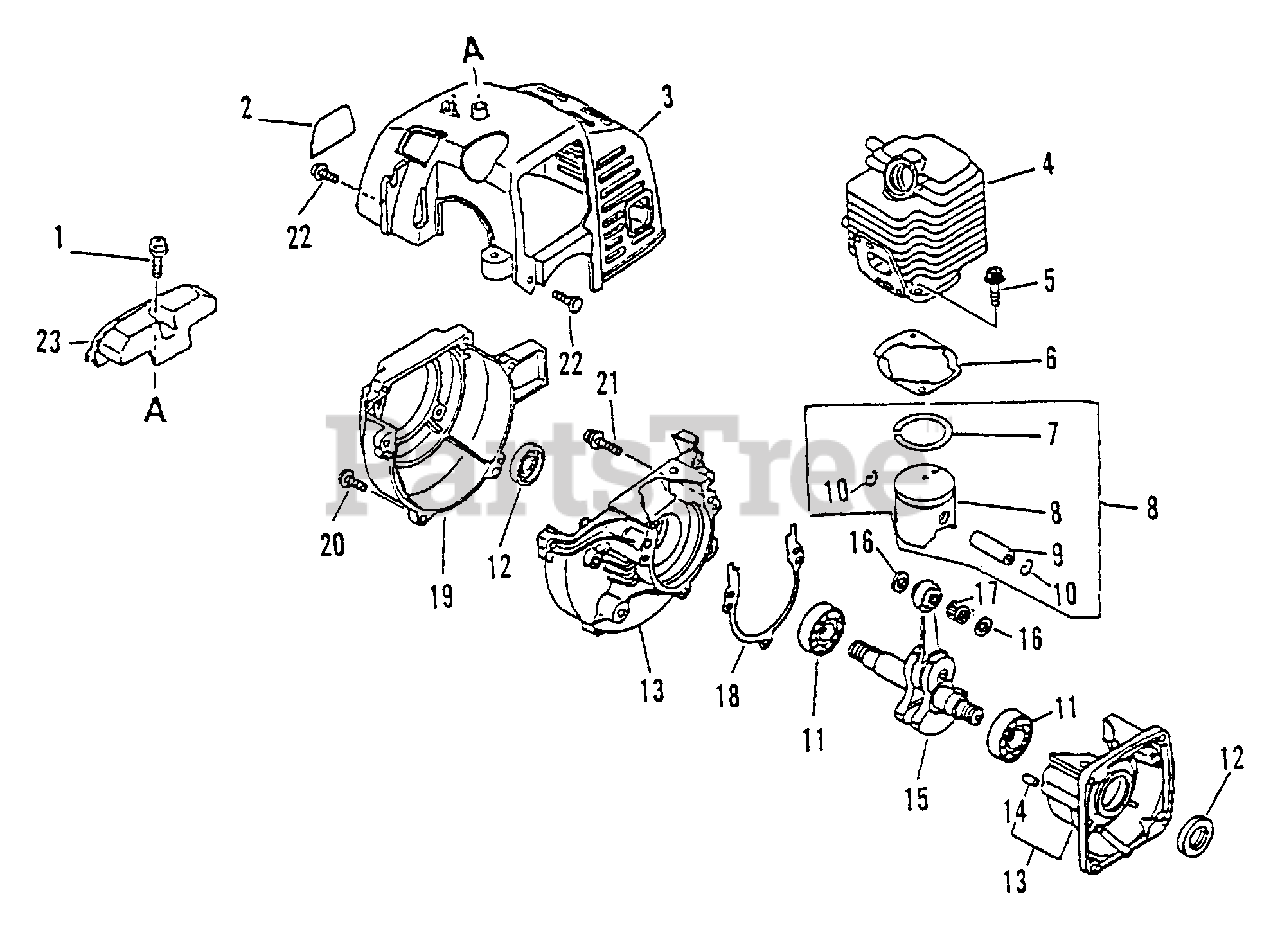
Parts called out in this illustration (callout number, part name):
1	SCREW - 5X16 -- TAPPING
2	LABEL - MODEL PE-2400
3	COVER, ENGINE - GRAY
4	CYLINDER
5	SCREW - 5X22
6	GASKET, CYLINDER
7	RING, PISTON
8	PISTON KIT
9	PIN, PISTON
10	RING, RETAINING
11	BEARING, BALL - 6201
12	SEAL, OIL
13	CRANKCASE KIT
14	PIN - LOCATING
15	CRANKSHAFT ASSY
16	SPACER, PISTON
17	BEARING, NEEDLE
18	GASKET, CRANKCASE
19	CASE, FAN - GRAY
20	SCREW - 4X16
21	SCREW - 5X28
22	SCREW - 4X12
23	GUARD, TOP - BLACK
